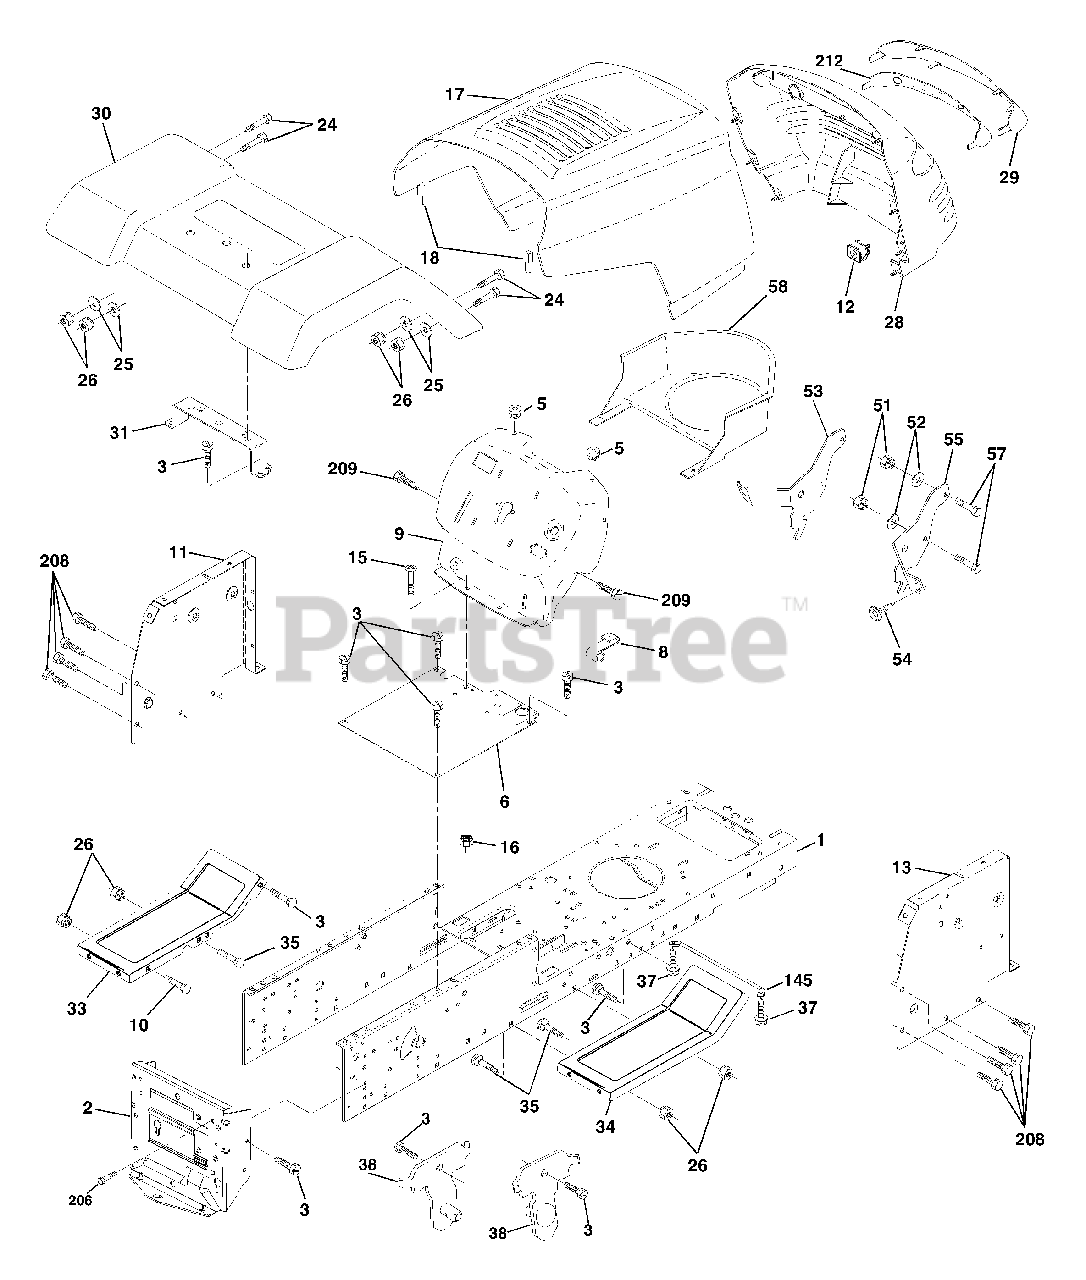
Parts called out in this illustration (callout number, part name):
1	Chassis Wldmt.
2	Drawbar Stretch 94
3	Screw Thdrol. 3/8-16 x 3/4
5	Bumper Hood/Dash
6	Saddle Flat Lt
8	Clip Retainer Slide-On
9	Dash Private Label
10	Bolt Rd Hd Sqnk. 3/8-16 Unc x 1
11	Panel Asm. Dash Lh
12	Clip Tinnerman Grile P/L
15	Screw Mach Trhd 5/16-18 Unc x 3/4
16	Nut Keps 5/16-18 Unc
17	Hood Pnt STL P/L w/trim
18	Bumper Hood
24	Bolt Fin Hex 3/8-16 Unc x 1 Gr. 5
25	Washer 13/32 x 13/16 x 12 Ga.
26	Nut Lock Hex w/Insert 3/8-16 UNC
28	Grill Private Lable Blk
29	Lens Grille Private label
30	Fender Asm LT
31	Bracket Fender
33	Footrest Pnt. Lh
34	Footrest Pnt. Rh
35	Bolt Rd Hd Sht. Sqnk. 3/8-16 x 3/4
37	Screw Thdrol 5/16-18 x 1/2 Tyt
38	Bracket Asm Pivot Mower Rear
51	Nut Lock Hex W/Ins. 1/4-20
52	Washer 9/32 x 7/8 x 16 Ga.
53	Bracket Grille LH
54	Screw Hex Wshd 8-18 x 7/8
55	Bracket, Grille RH
57	Bolt Fin Hex 1/4-20 x .75
58	Air Duct Private Label
145	Rod Pivot Chassis/Hood
206	Bolt Shoulder 5/16-18
208	Screw Thdrol 3/16 x 1/2
209	Screw Hexwsh Thdr 3/8-16
